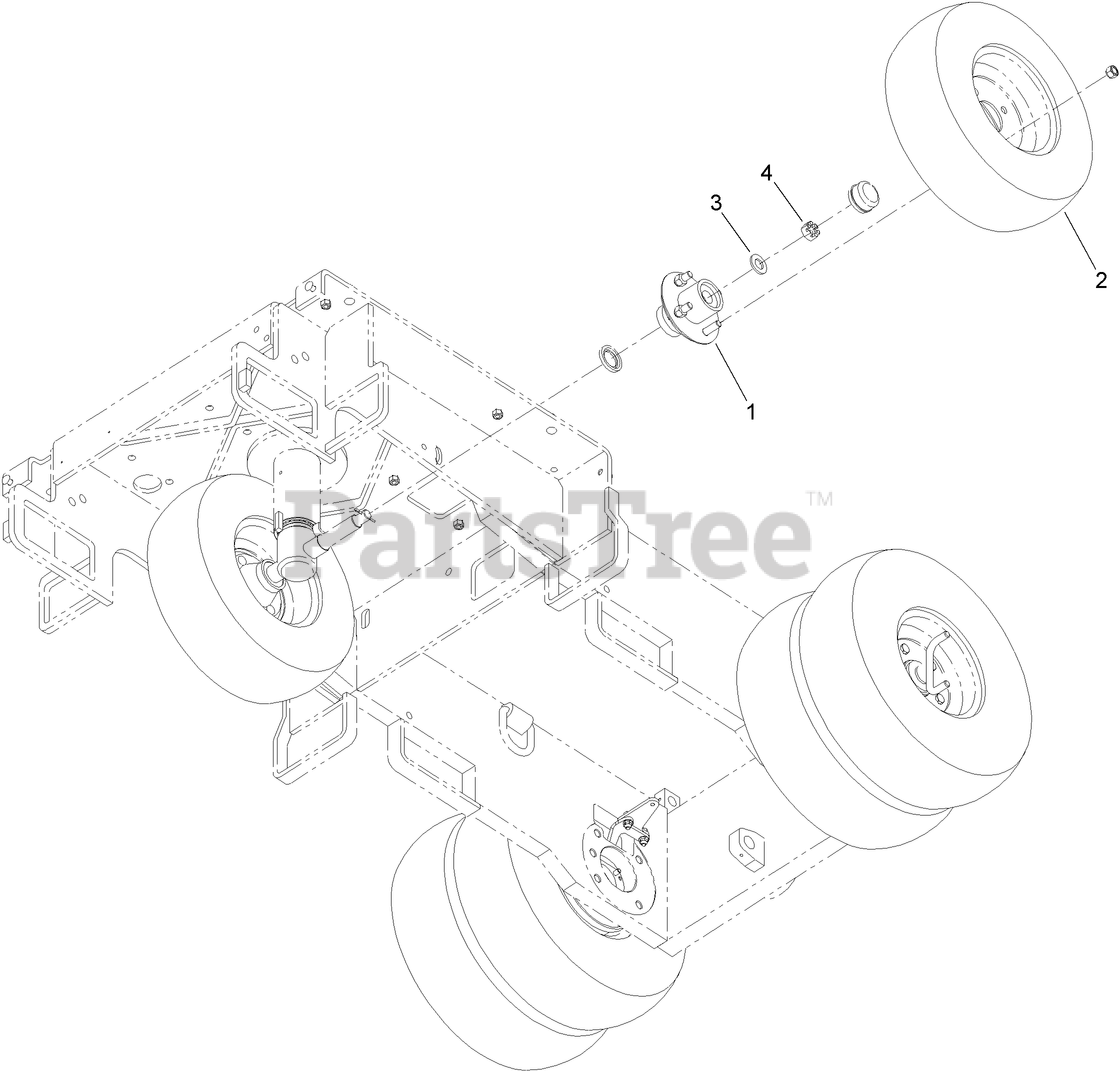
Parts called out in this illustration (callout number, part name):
1	HUB ASM
2	WHEEL ASM (WITH FOAM)
3	WASHER-FLAT
